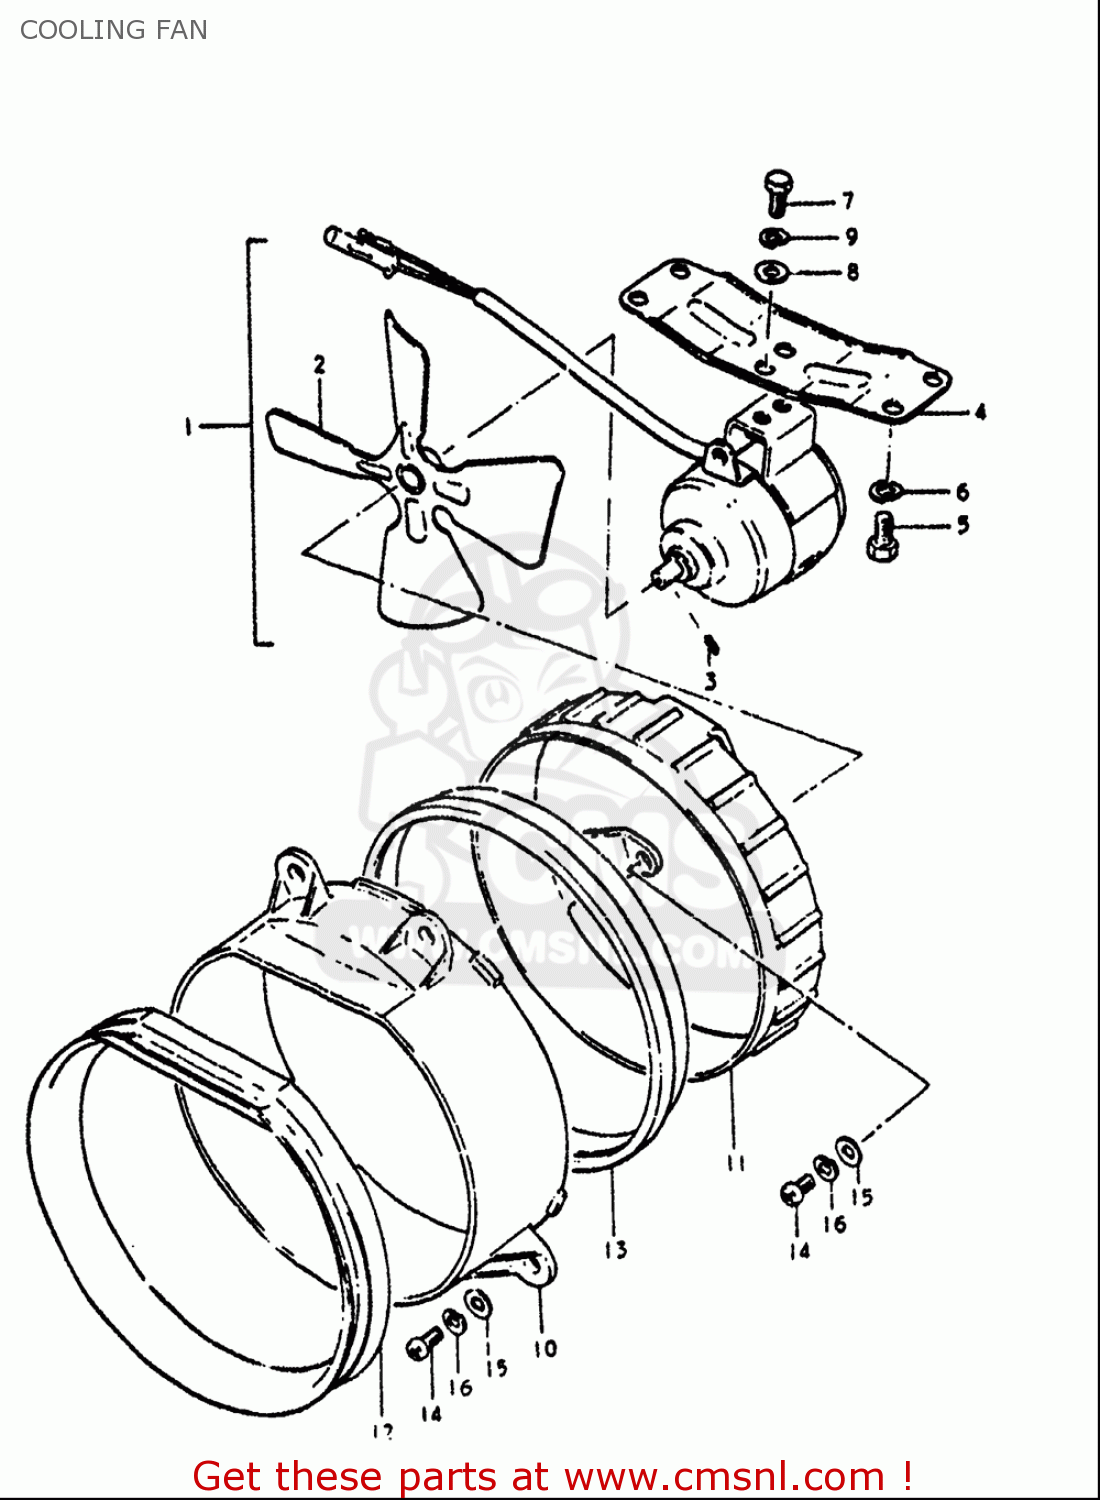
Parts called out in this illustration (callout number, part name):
3	SCREW
5	BOLT
6	WASHER,LOCK
7	BOLT
8	WASHER
9	WASHER,LOCK
14	SCREW
15	WASHER
16	WASHER,LOCK
